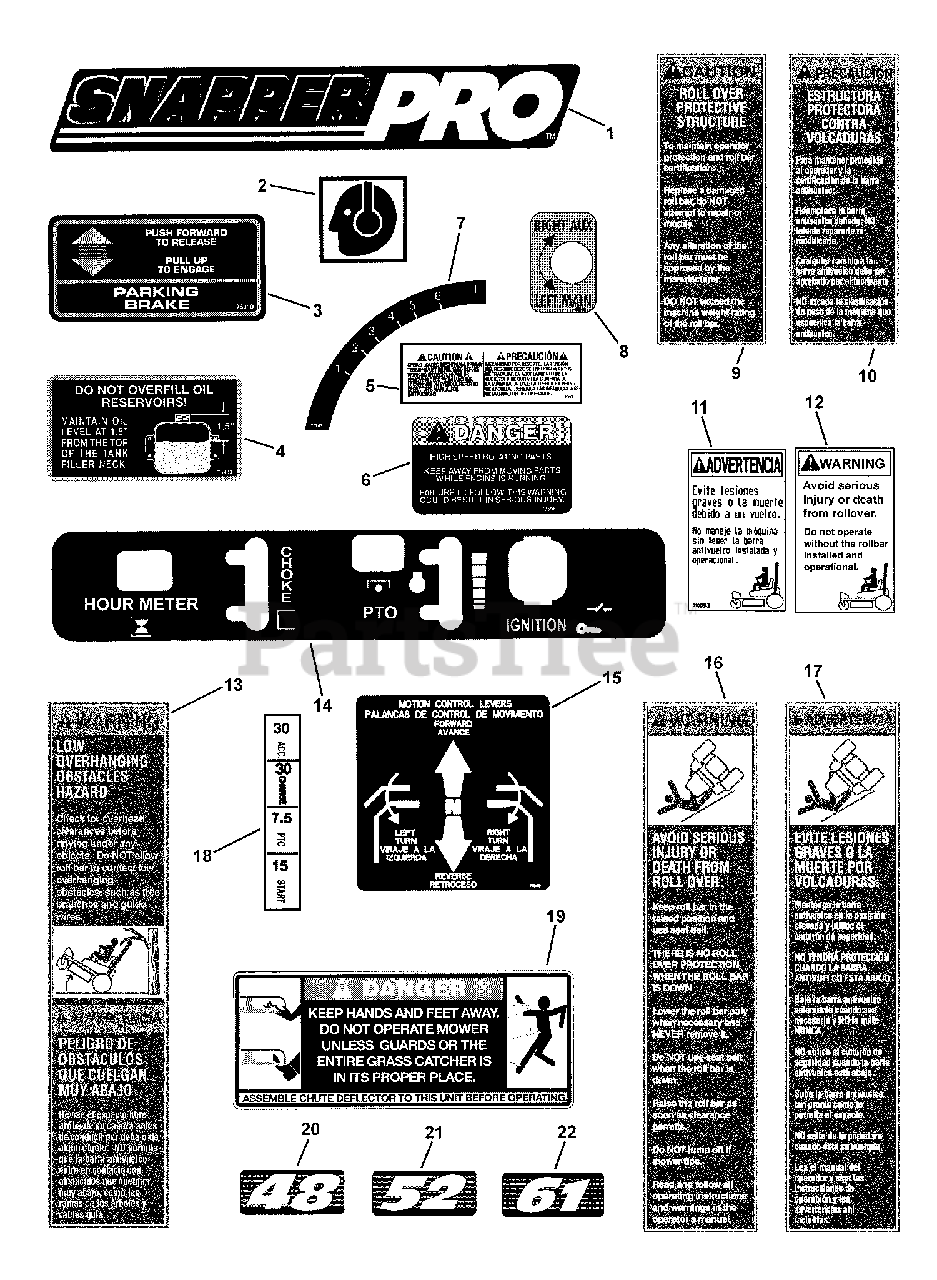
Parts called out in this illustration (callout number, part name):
1	DECAL, Snapper Pro
2	DECAL, Ear Protection
3	DECAL, Park Brake
4	DECAL, Oil Reservoir Overfill Warning
5	DECAL, Caution (Spring Mechanism)
6	DECAL, Danger (High Speed Rotating Parts)
7	DECAL, Detent
8	DECAL, Tank Selector
9	DECAL, Caution ROPS
10	DECAL, Caution ROPS (Spanish)
11	DECAL, Warning (SP)
12	DECAL, Warning, Rollbar
13	DECAL, ROPS Overhang
14	DECAL, Control Panel
15	DECAL, Motion Control Levers
16	DECAL, Warning ROPS
17	DECAL, Warning ROPS (Spanish)
18	DECAL, Fuse Block
19	DECAL, Danger, Guard/Catcher
20	DECAL, 48" Deck, (silver)
21	DECAL, 52" Deck (silver)
22	DECAL, 61" Deck (silver)
